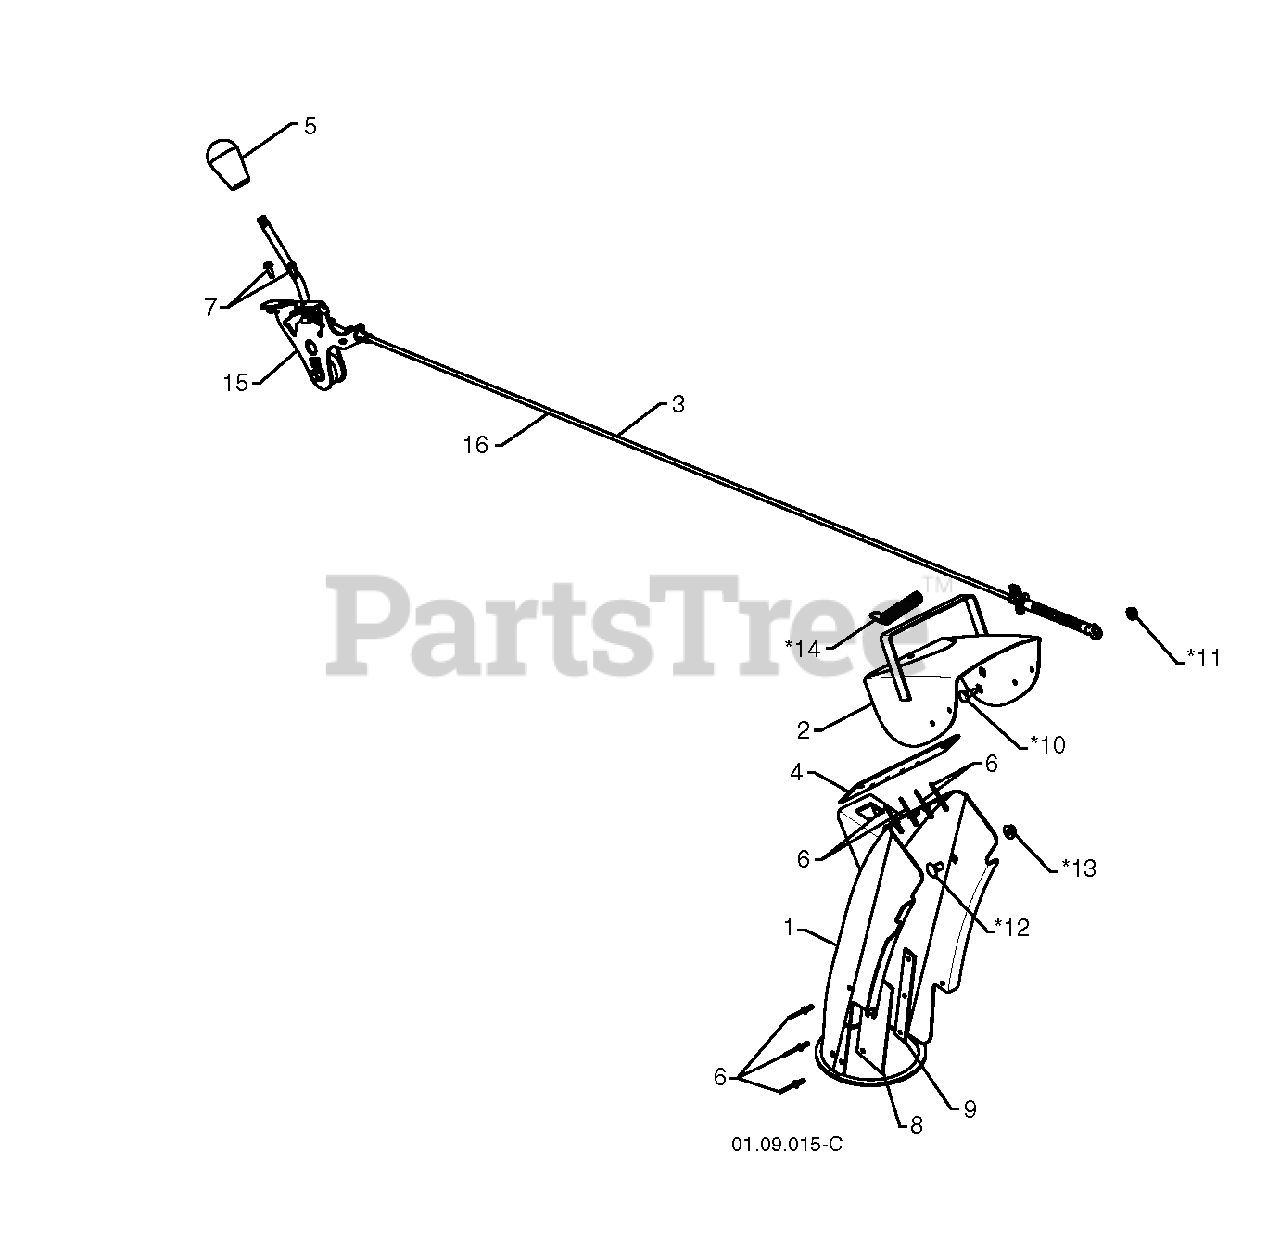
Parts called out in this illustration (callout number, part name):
1	RP_CHUTE.WELDMENT.SNOW.ORANGE
2	DEFLECTOR.WELDMENT.PNT.ORANGE
3	RP.CONTROL.ASM.DEFLECTOR.SNOW
4	SEAL.DEFLECTOR
5	KNOB LEVER, BLACK
6	RIVET BLIND
7	SCREW #10-24 X 5/8
8	SHIELD.SNOW.CHUTE
9	STRAP.SHEILD.RETAINER
10	BOLT, SHOULDER
11	NUT.HEX.FLANGE.1/4
12	BOLT
13	NUT.LOCK.5/16-18
14	SPRING.DEFLECTOR.REM.CHUTE
15	RP CNTRL.HEAD.ASSEM.DEFLECTOR
16	RB SERVICE.CHUTE.DEF.CBL.BLK
